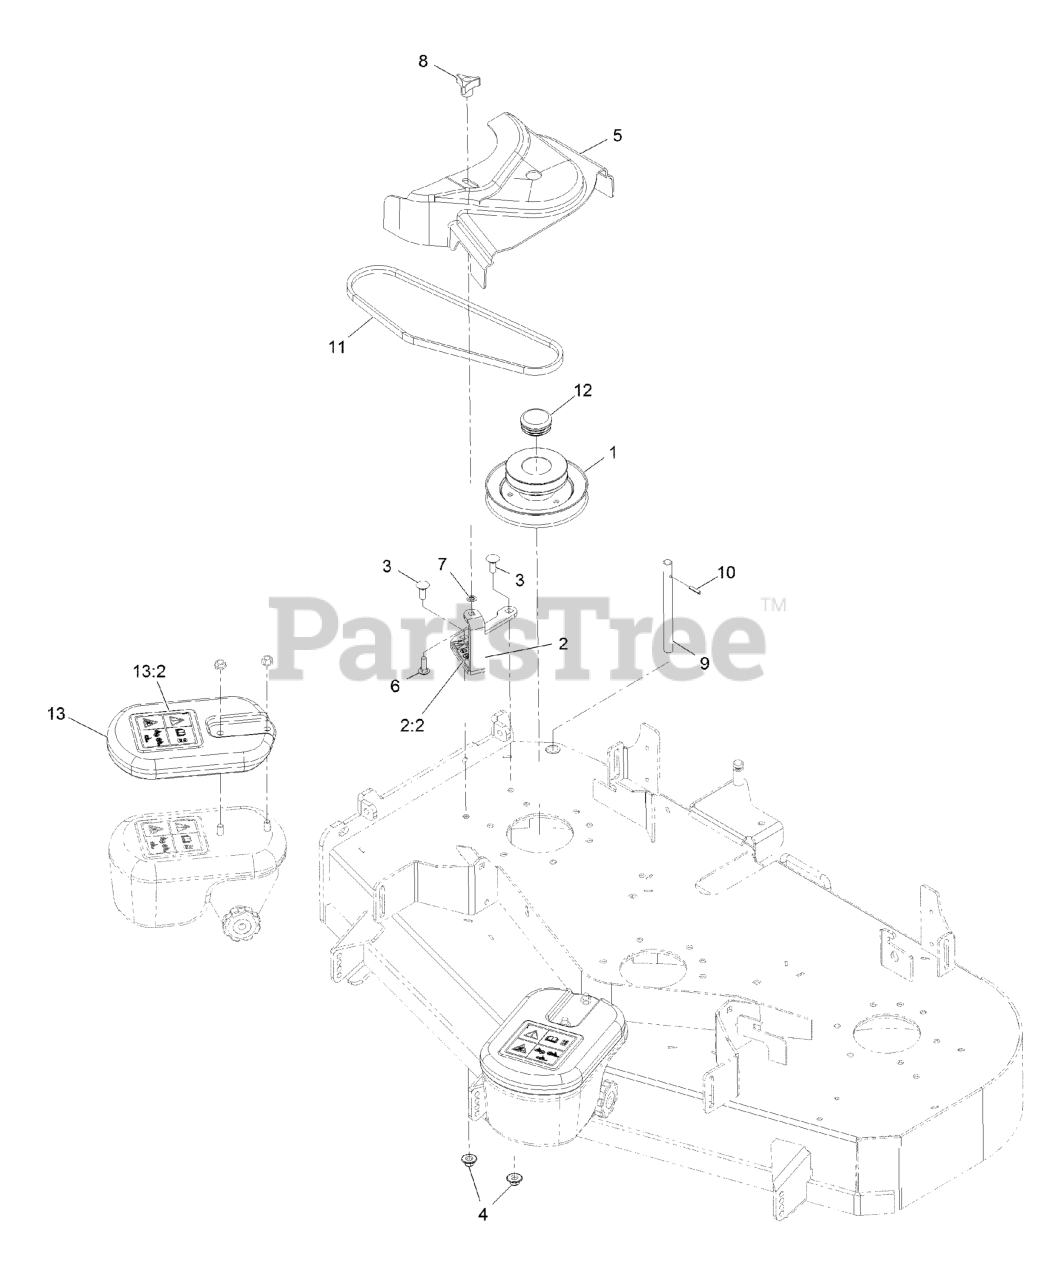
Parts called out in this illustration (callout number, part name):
1	JACKSHAFT-UV DRIVE, 484 SPLINED
2	ASM-CVR BRKT W/DECAL
2:2	DECAL-DANGER
3	BOLT-CARR
4	Nut-Nyloc 3/8-16 Flg
5	COVER-BELT, UV 48 ENTRY
6	BOLT-CARR
7	RING-RETAINING, BOLT
8	KNOB-3 PRONG
9	SHAFT-CATCHER, GRASS
10	PIN-ROLL
12	PLUG-ROUND PLASTIC
13:2	DECAL-WARNING, TRACTION
